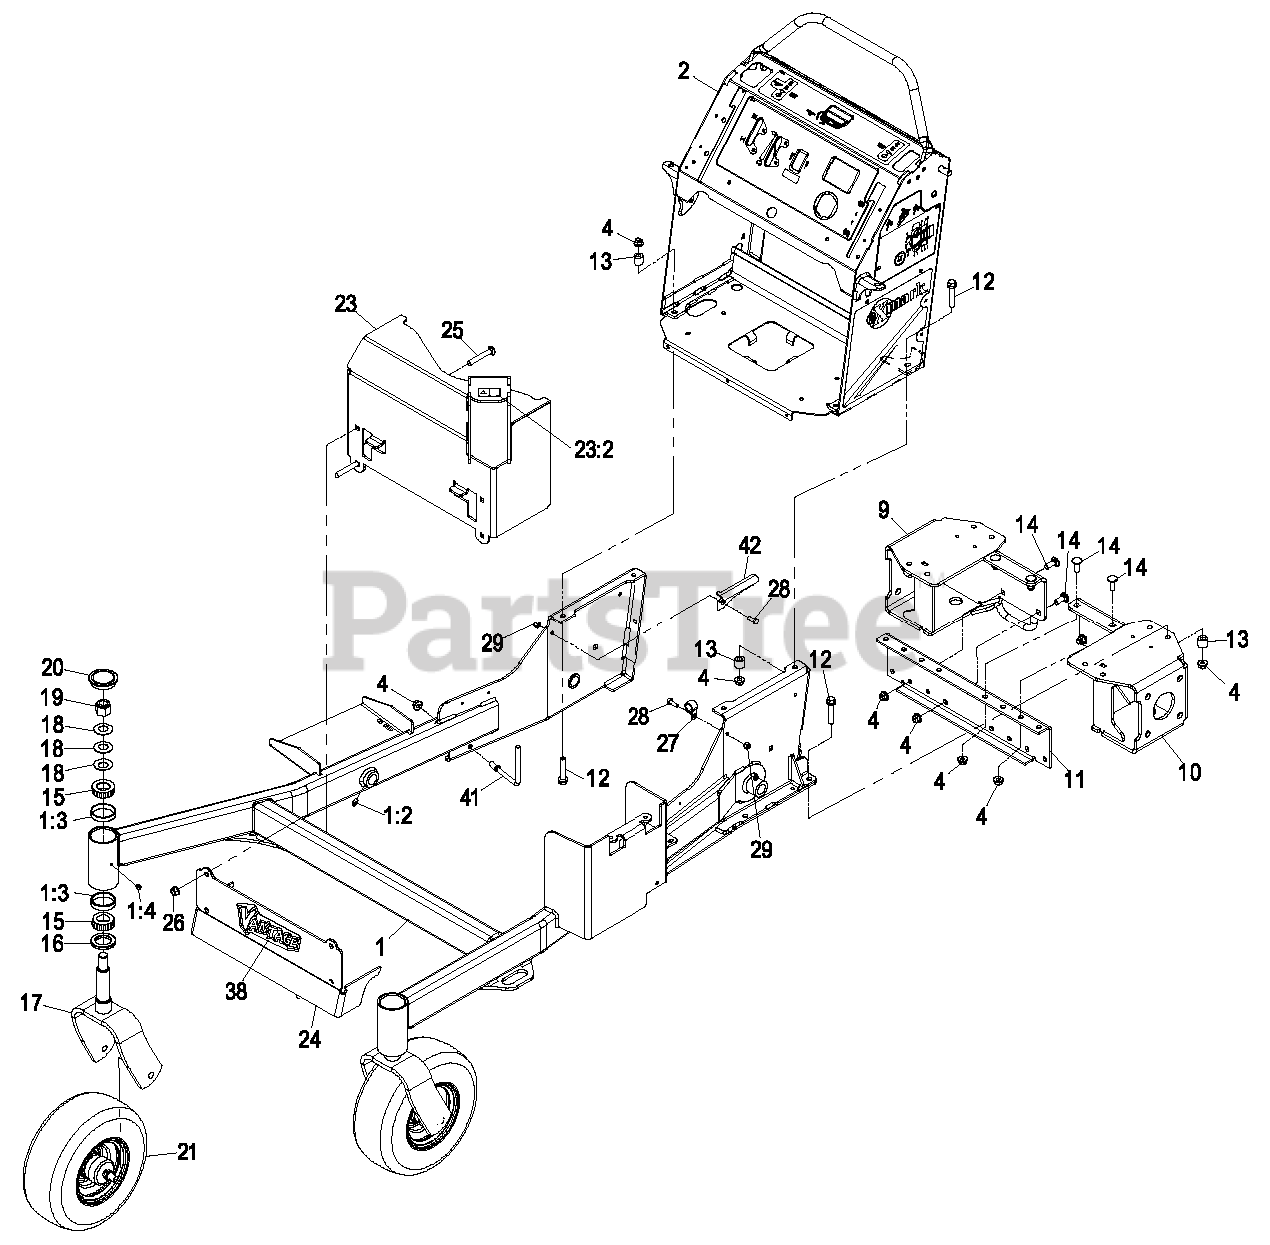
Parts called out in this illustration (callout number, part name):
1:2	FITTING-GREASE
1:3	CUP-BEARING
4	NUT-HF, NI
9	RH MOTOR MOUNT ASM
10	LH MOTOR MOUNT ASM
11	MOUNT-MOTOR, CENTER
12	SCREW-HHF
14	SCREW-CARR
15	Cone-Bearing Tapered Roller
16	SEAL-GREASE
17	FORK-CASTER
18	WASHER-BELLVILLE
19	NUT-LOCK, NI
20	CAP-GREASE
21	WHEEL/TIRE AND BEARING AS
23	MUFFLER GUARD ASM
23:2	DECAL-WARNING
24	PANEL-GUARD
25	SCREW-CARR
27	CLAMP-CABLE
28	SCREW-HH
29	NUT-LOCK, NI
38	DECAL-VANTAGE LOGO
41	GUIDE-HOSE, SUPPORT
42	BRACKET-HOSE, FUEL
